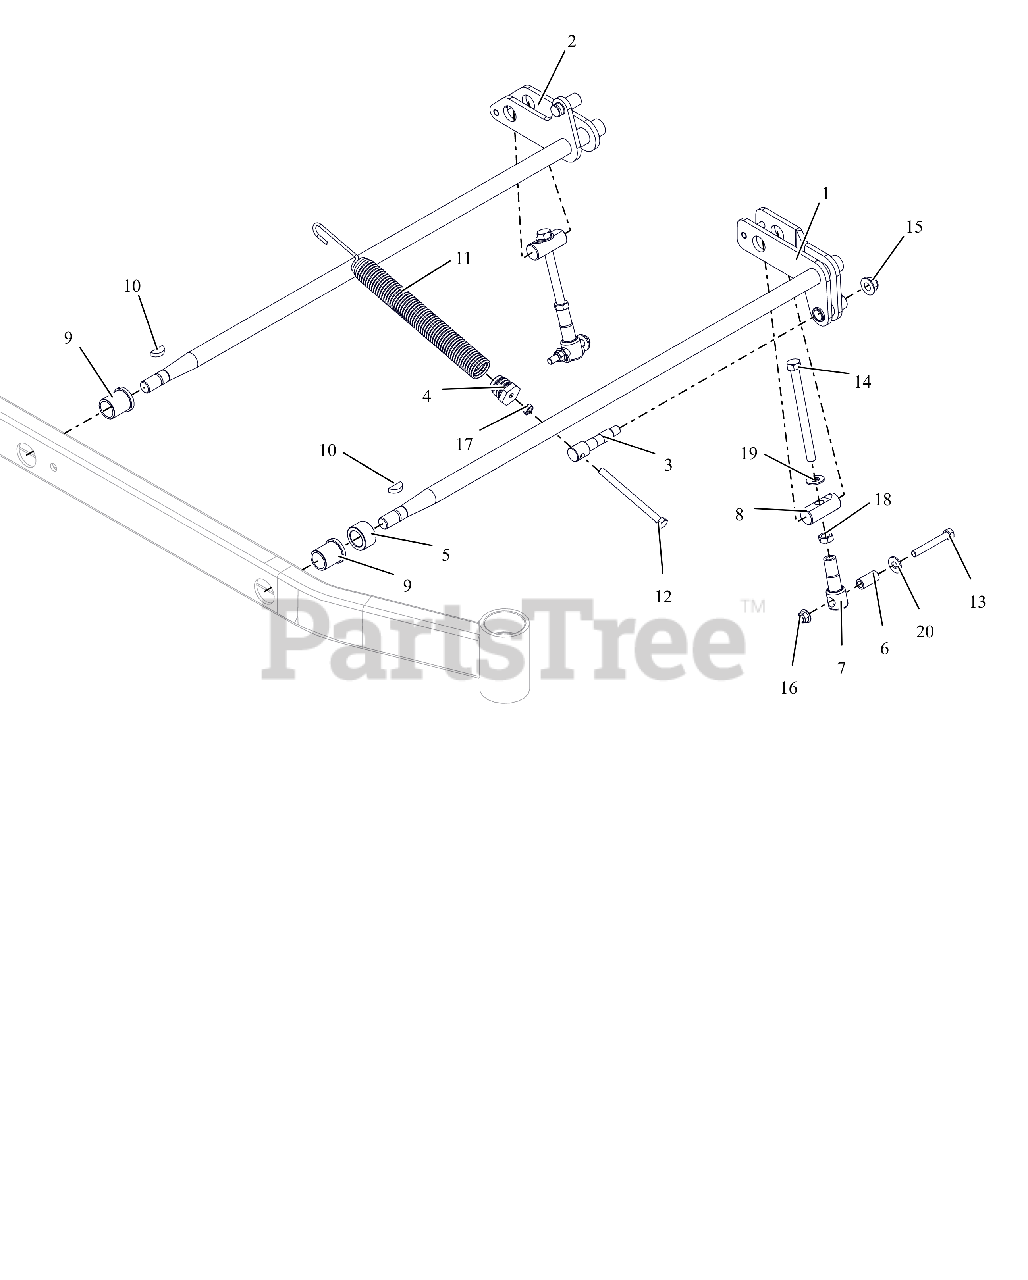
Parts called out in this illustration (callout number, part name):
1	FRONT LH DECK LIFT ARM WMT-LF
2	WLM, REAR LH DECK LIFT ARM-LF
3	TRUNION, DECK LIFT SPRING
4	PLUG, SPRING
5	SPACER, 1.500 X 1.000 X .880
6	SPACER, DECK LEVELING
7	LINK, DECK LIFT FORMED
8	PIN, DECK LIFT
9	BSHG-FLG 1.00X1.25X1.50X1.50
10	KEY-WDRF .25X1.00 HRD #15
11	SPRING, DECK LIFT
12	BLT, HEX .38-16X5.00F G5 ZCC
13	BLT, HEX .38-16X2.75 G8 ZCC
14	BLT, HEX .50-13X6.00S G5 ZCC
15	NUT,NYL-FLG .50-13 GF ZCC
16	NUT,NYL-FLG .38-16 GF ZCC
17	NUT-JAM .375-16 G2 ZCC
18	NUT-JAM .500-13 G2 ZCC
19	WSHR, FLT .557X1.040X.102 ZCC
20	WSHR,FLT .438X1.00X.083 ZCC
